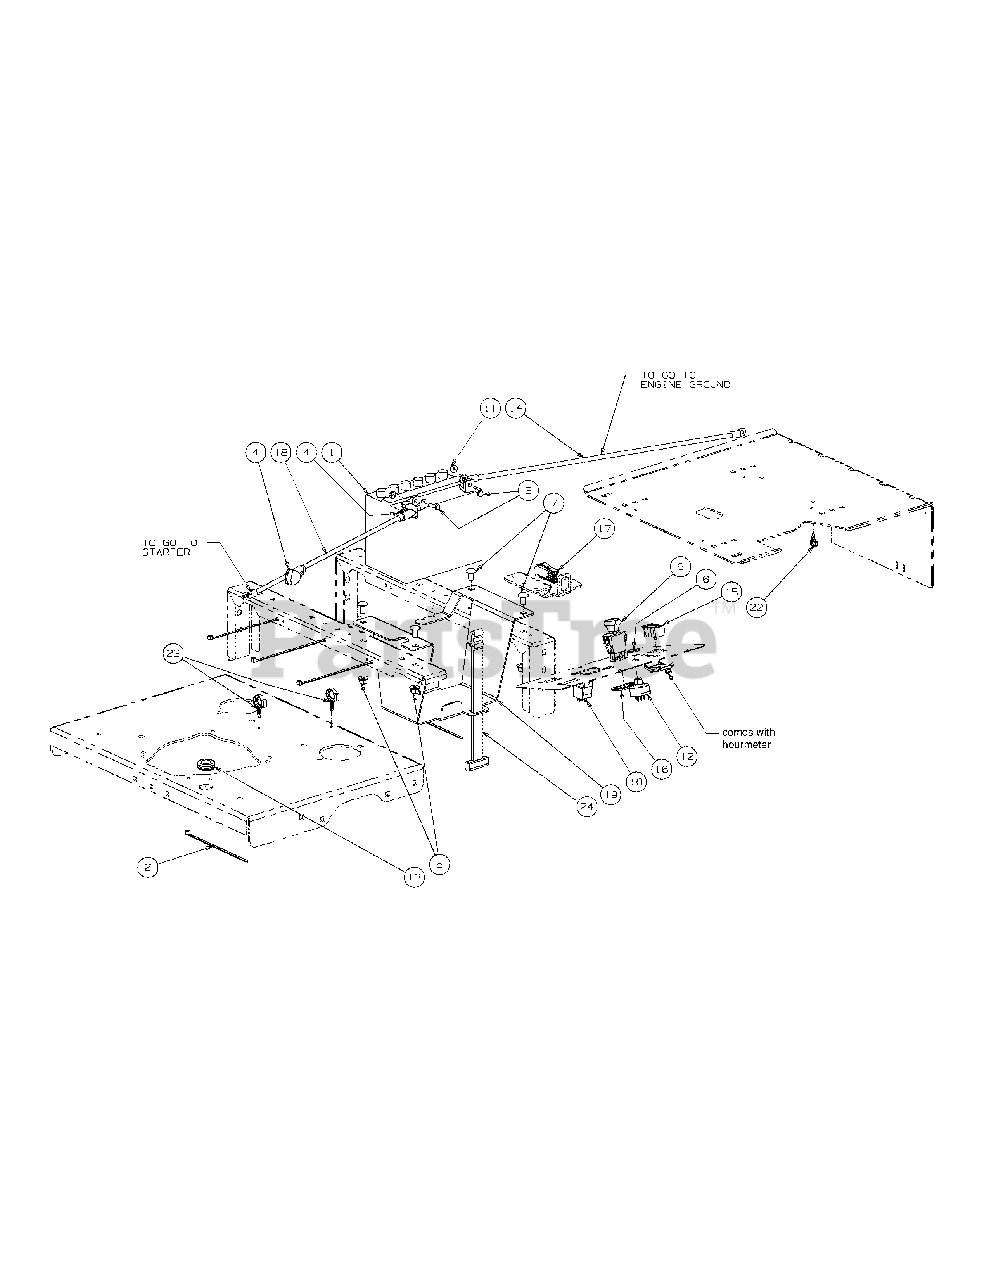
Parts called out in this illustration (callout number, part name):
1	Battery, 12V 225CCA 30 Min
2	Tie, Cable, 3/16 x .05 x 7.4"
3	Screw, Hex, Cap, 1/4-20 x .75
4	Boot, 1" OD Rubber Battery-PST, Red
5	Hex Nut, Flange Lock, 3/8-16
6	Nut, W/Cap, 5/8-32 Ignition
7	Carriage Bolt, 3/8-16 x .75 Long
9	Switch, Electric, PTO
10	Relay, 12V 40A
11	Hex Flange Lock Nut, 1/4-20
12	Switch, Ignition, 6 Pin includes:
13	Grommet, .75 ID
14	Cable, Battery Black, 28"
15	Meter, Hour includes:
16	Bracket, PTO Switch Retainer
17	Switch, Safety N.O./N.C.
18	Cable, Battery Red, 42"
19	Battery Bracket
20	Wire Harness Adaptor
22	Electrical Conduit Clip, 3/8
23	Electrical Conduit Clip, 5/8
24	Strap, Battery
